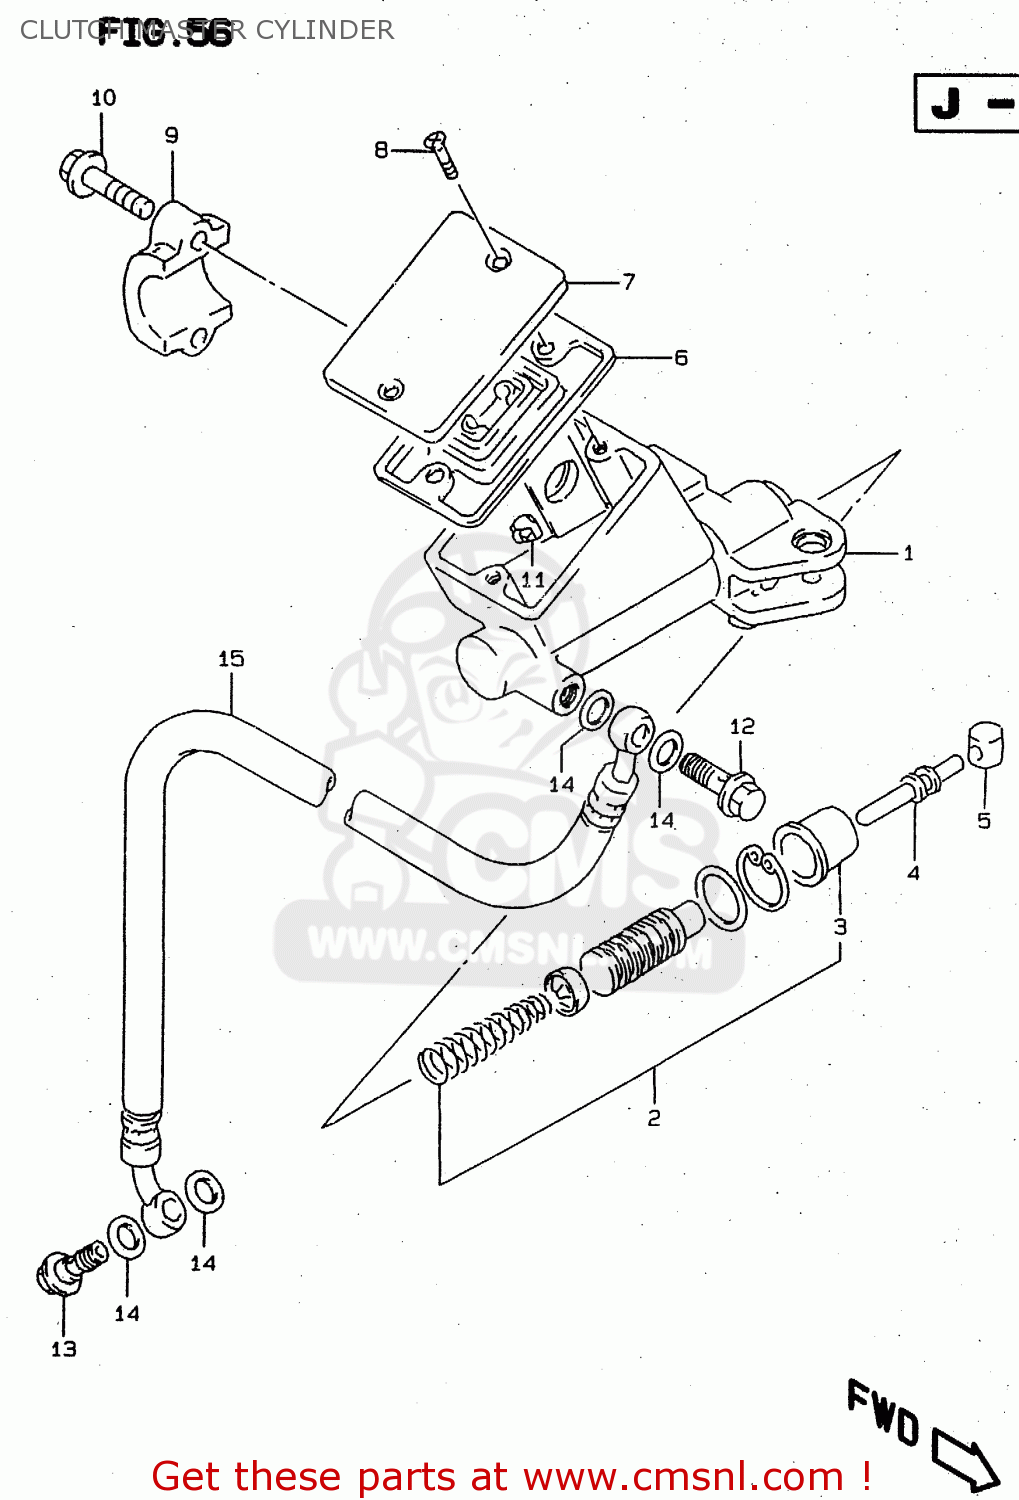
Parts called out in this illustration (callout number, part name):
1	CYLINDER ASSY,CLUTCH MASTER
2	PISTON & CUP SET
3	BOOT
4	ROD,PUSH
5	BUSH
6	DIAPHRAGM
7	CAP
8	SCREW
9	HOLDER
10	BOLT(6X25)
11	PROTECTOR
12	BOLT UNION
13	BOLT UNION
14	WASHER(10X15X1.5)
15	HOSE COMP,CLUTCH
